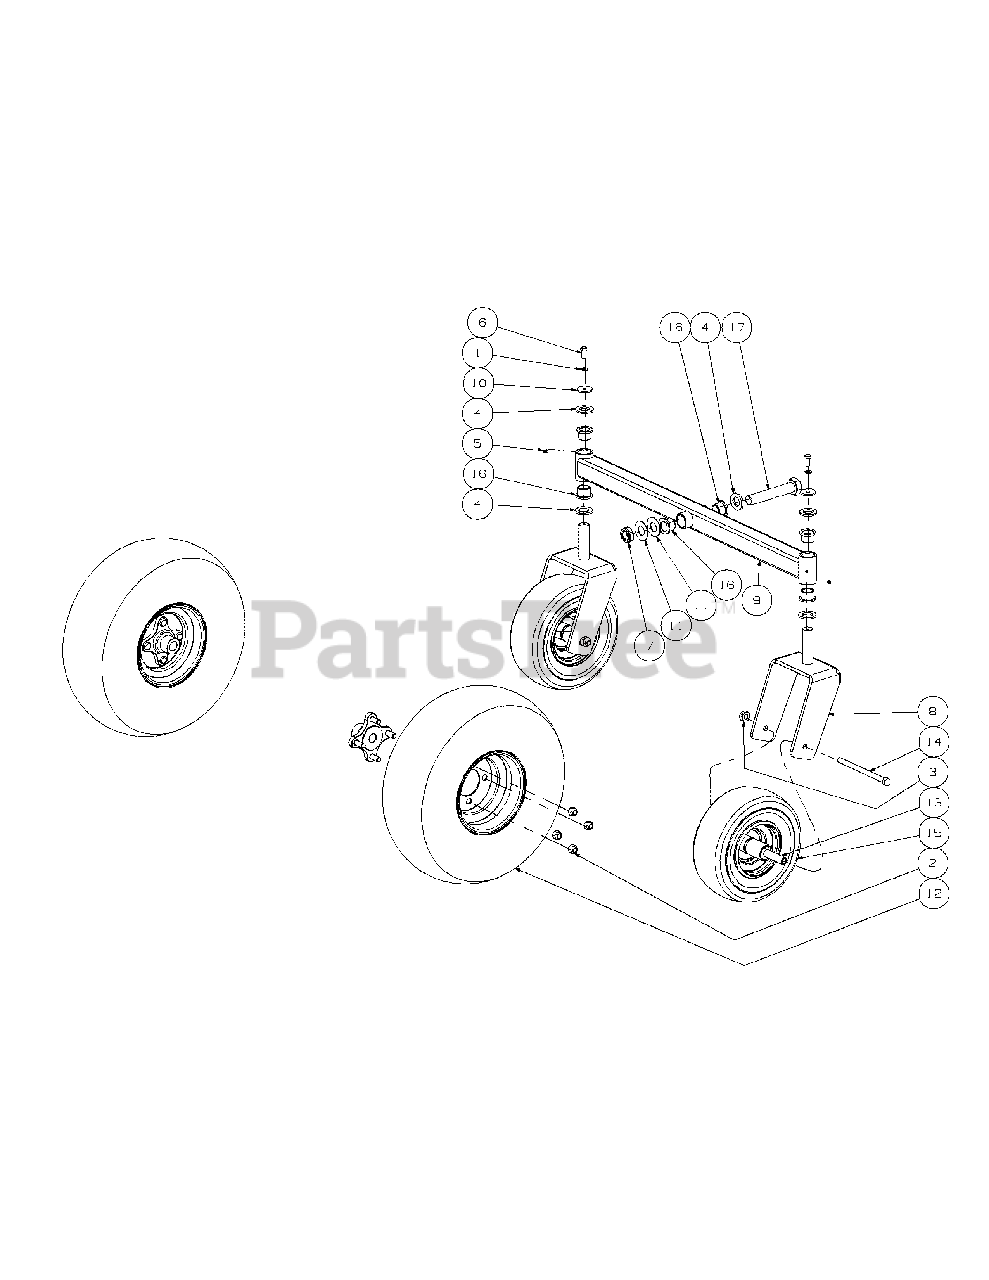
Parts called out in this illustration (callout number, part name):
1	Lock Washer, 3/8 Zinc
2	Lug Nut, 1/2-20
3	Lock Nut, Nylon Insert, 1/2-20
4	Washer Special
5	Grease Fitting, 1/4-28 x 3/16
6	Hex Cap Screw, 3/8-16 x .88
7	Nut Jam, 1.0-14, Nylon Insert
8	Castor Wheel Mounting Bracket
9	Front Axle Assembly
10	Flat Washer, .390 x 1.5 x .134
11	Flat Washer, 1.00 ID x 2.25 OD x ,075
12	Wheel Assembly, 20 x 8-10 NHS
13	Wheel Spacer
14	Hex Cap Screw, 1/2-20 x 7.50
15	Wheel Assembly 11 x 6.00 - 5, Beige
16	Flange Bearing, 1.001 x 1.25
17	Hex Cap Screw, 1-14 x 5.5
